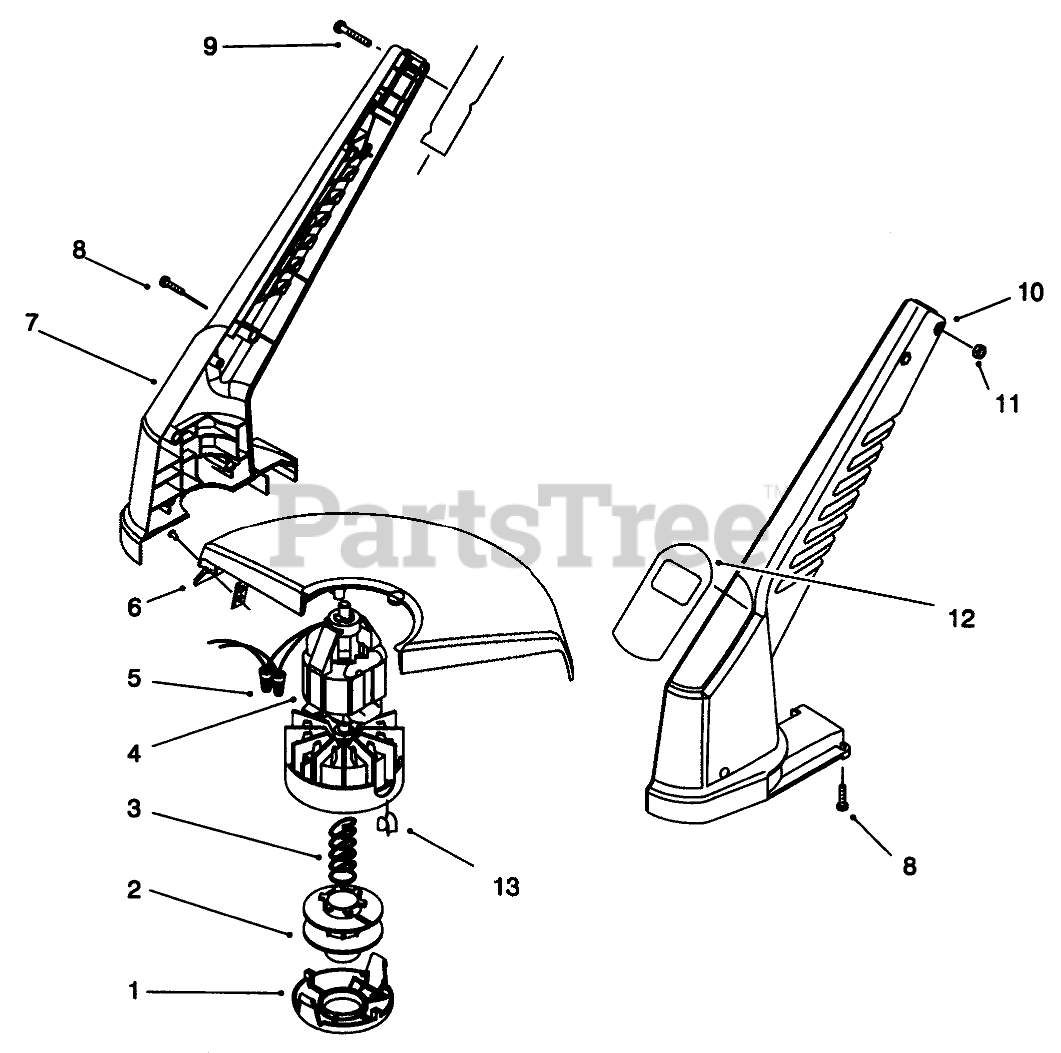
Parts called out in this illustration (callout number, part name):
2	SPOOL-LARGE
3	SPRING-COMPRESSION
4	Motor Assembly (Incl. Ref. #13)
5	CONNECTOR-NUT, WIRE
6	SHIELD ASM - SERVICE
7	RH HOUSING
8	SCREW-PPH
9	SCREW-PPH
10	LH HOUSING
11	NUT-HEX
12	DECAL - 14" TRIMMER
13	EYELET
